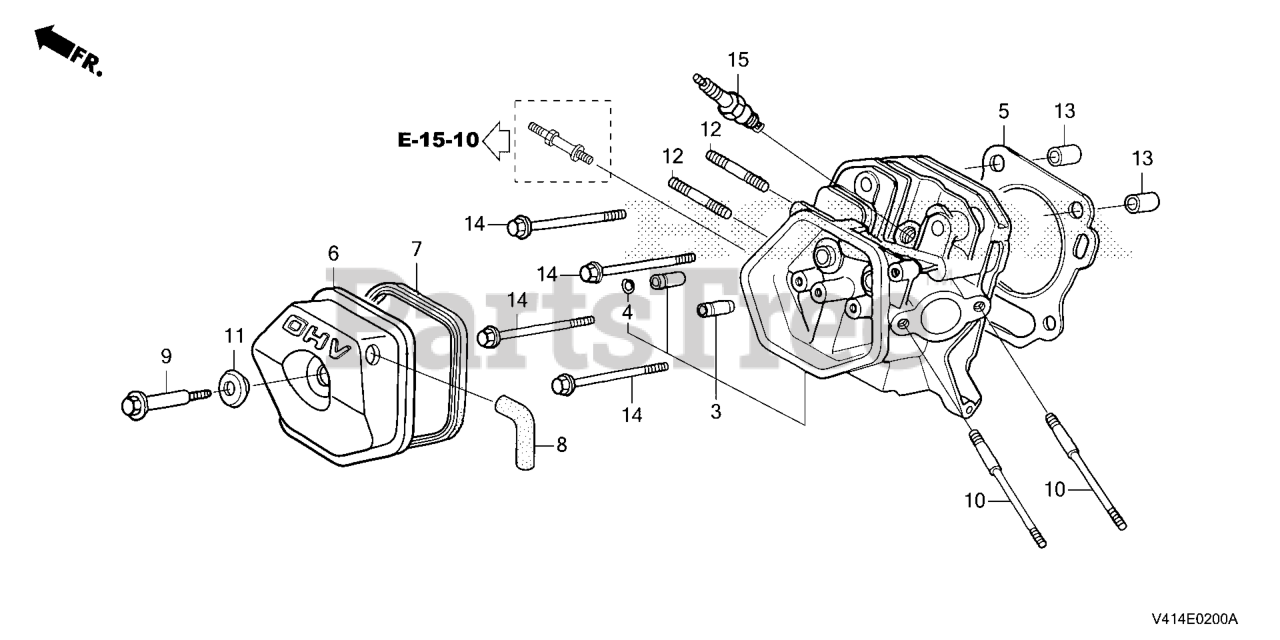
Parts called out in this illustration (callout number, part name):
3	CYLINDER HEAD
4	CLIP, VALVE GUIDE
5	GASKET, CYLINDER HEAD (NIPPON LEAKLESS)
6	COVER, HEAD
7	GASKET, CYLINDER HEAD COVER
8	TUBE, BREATHER
9	BOLT, HEAD COVER
10	BOLT, STUD (8X134.5)
11	WASHER, HEAD COVER
12	BOLT 2, STUD (8X32)
13	PIN A, DOWEL (12X20)
14	BOLT, FLANGE (10X80)
15	SPARK PLUG (BPR5ES) (NGK)
